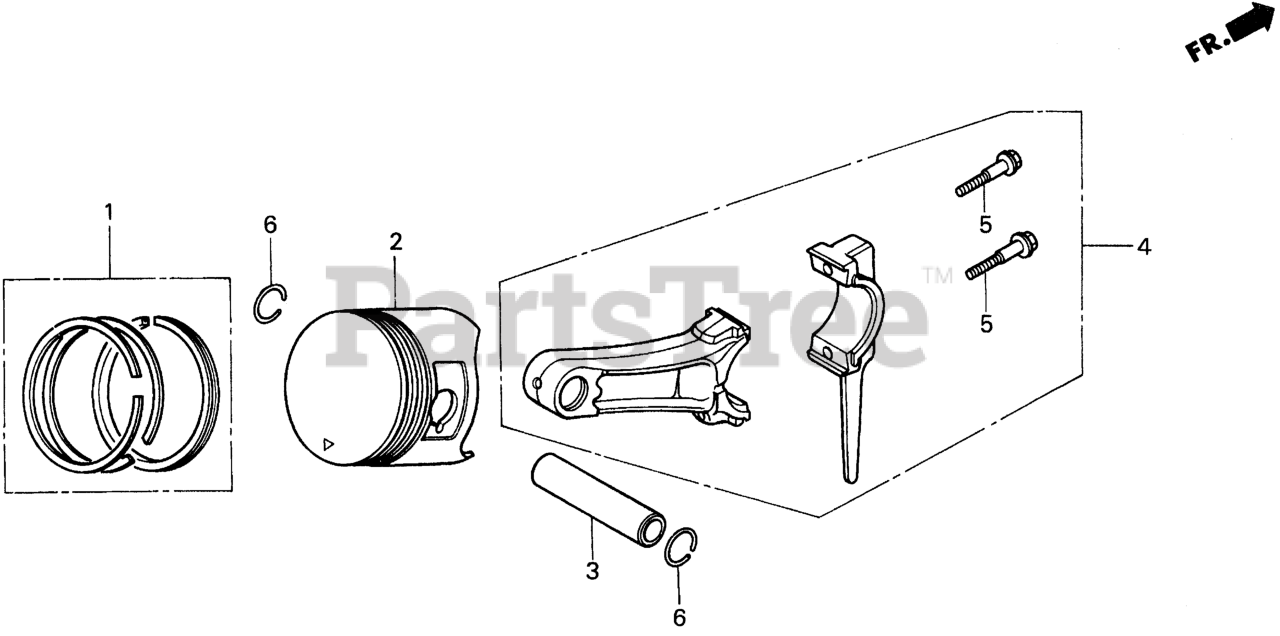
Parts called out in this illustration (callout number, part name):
1	RING SET, PISTON (STD)
1	RING SET, PISTON (OS 0.25)
1	RING SET, PISTON (OS 0.50)
1	RING SET, PISTON (0.75)
1	RING SET, PISTON (0.75) (TEIKOKU)
2	PISTON (STD)
2	PISTON (OS 0.25)
2	PISTON (OS 0.50)
2	PISTON (0.75)
3	PIN, PISTON
4	ROD ASSY., CONNECTING (US 0.25)
4	ROD ASSY., CONNECTING (STD)
5	BOLT, CONNECTING ROD
6	CLIP, PISTON PIN (20MM)
